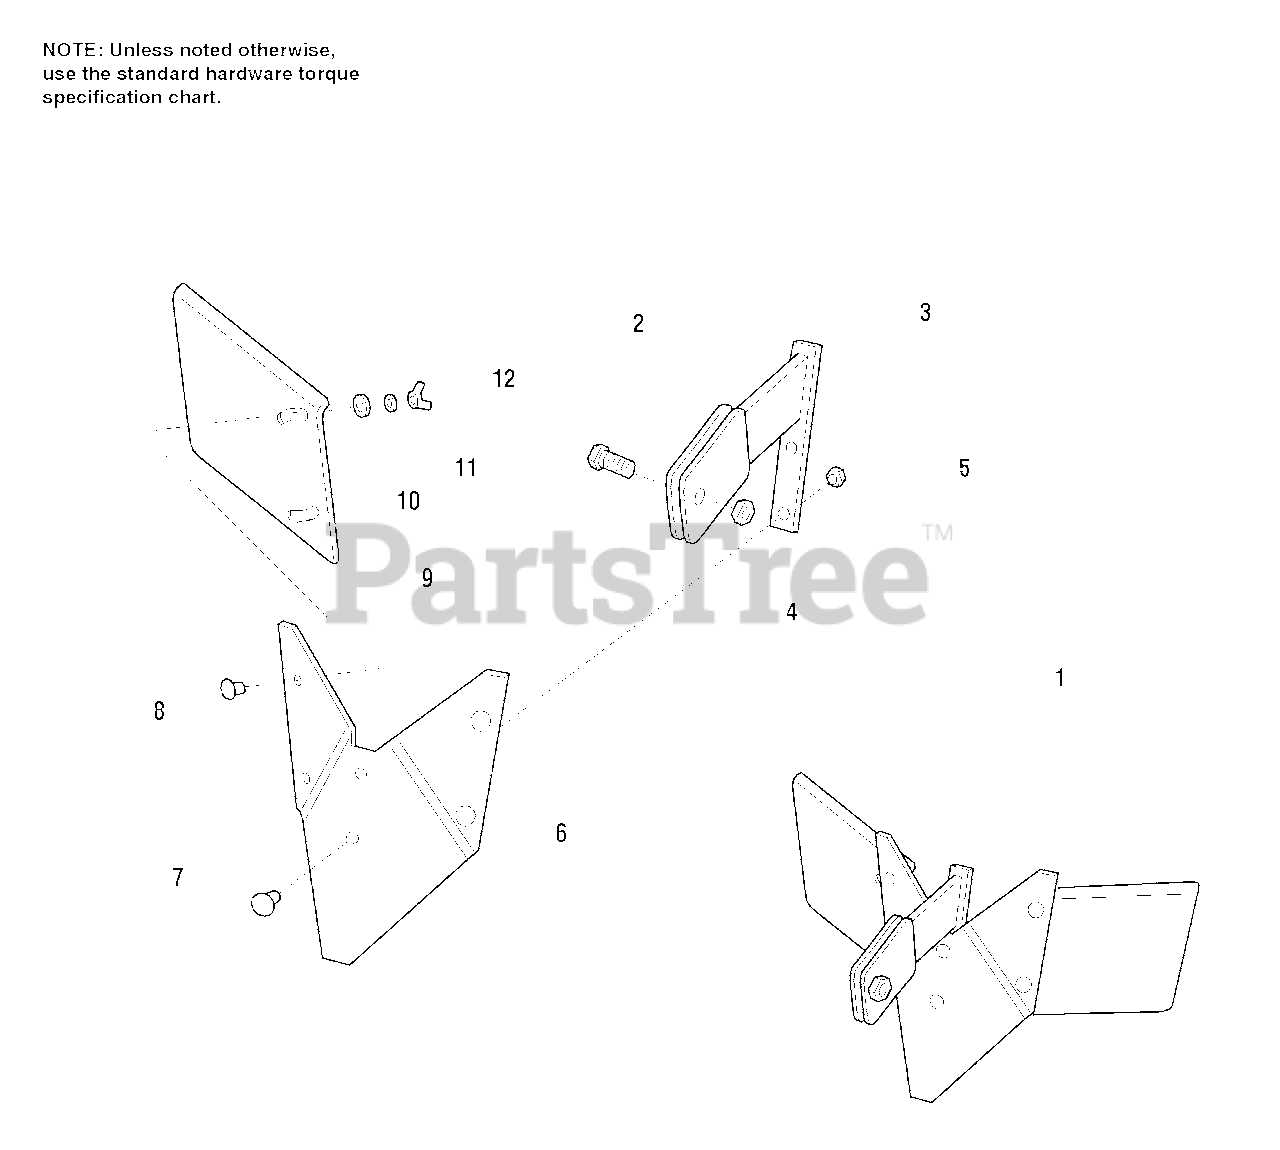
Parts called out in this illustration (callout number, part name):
1	HILLER/FURROWER
3	BRACKET
6	BLADE, Furrower
9	HILLER WING, Left
